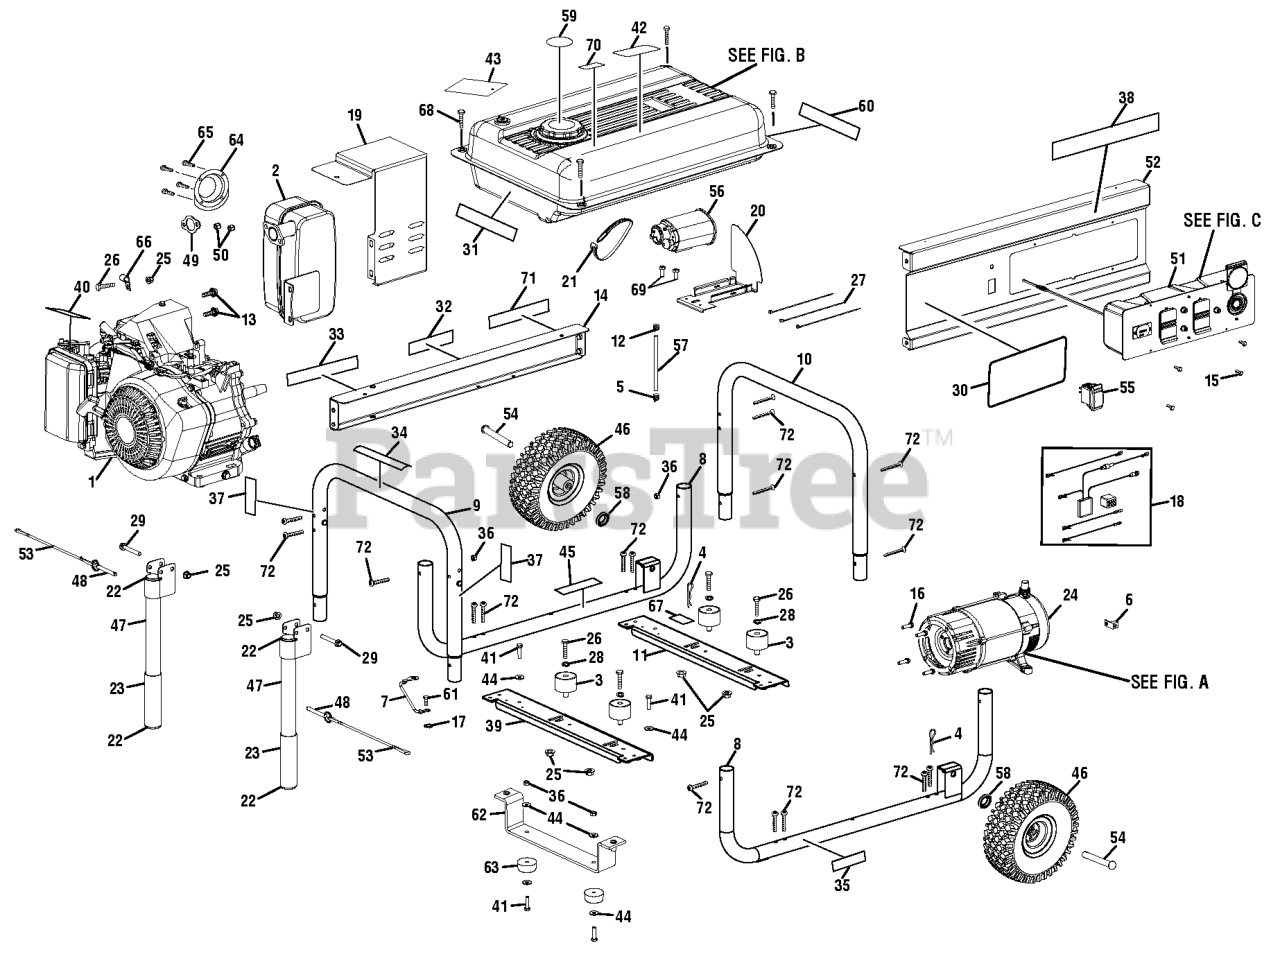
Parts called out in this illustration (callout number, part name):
1	Engine (Subaru)
4	Hitch Pin
5	Clamp (3/8 in.)
6	Ground Lug
7	Ground Wire Assembly
8	Lower Frame Assembly
9	Tube Assembly (Left)
10	Tube Assembly (Right)
11	Gen. Head Cross Brace
12	Clamp (1/2 in.)
13	Bolt (5/16-24 x 5/8 in.)
14	Back Panel
15	Screw (6-20 x 3/8 in.)
16	Bolt (3/8-16 x 1.25 in.)
17	Star Washer (M6)
18	Wire Harness
19	Heat Shield
20	Bracket (Carbon Canister)
21	Cable Tie (18.6 in.)
22	Plastic Cap
23	Handle Grip
24	Generator Head w/AVR
25	Lock Nut (M8)
26	Bolt (M8 x 35 mm, Hex Hd.)
27	Tie Wrap (5.5 in.)
28	Washer (M8)
29	Bolt (M8 x 55 mm, Hex Hd.)
30	Logo Label
31	Electric Start Label
32	Hot Surface Label
33	Danger Label
34	Fire Danger Label
35	Engine Lubricant Label
36	Lock Nut (M6)
37	Locking Pin Label
38	Subaru Label
39	Engine Cross Member
40	Choke Label
41	Bolt (M6 x 1 in., Hex Hd.)
42	CPSC Label
43	Danger Hang Tag
44	Washer (ID6.4 x OD17 x 1.6t)
45	Combustion Warning Label
47	Handle Assembly
48	Release Pin (5/16 x 2 in.)
49	Exhaust Gasket
50	Lock Nut (M8)
51	Panel Assembly
52	Front Panel
55	Start Switch w/Lock
56	Carbon Canister Assembly
57	Purge Hose
58	Washer (1/2 in.)
59	Fuel Stabilizer Label
60	Ground Warning Label
61	Screw (M6 x 16 mm, Hex Hd.)
62	Foot Bracket
63	Rubber Foot
64	Spark Arrestor
65	Screw (8-32 x 3/8 in., Pan Hd.)
66	J-Clamp (1/2 in.)
67	Ground Label
68	Screw (1/4-14 x 1-1/4 in.)
69	Screw (#10-16 x 3/4 in.)
70	E85 Label
71	Fire Distance Label
72	Screw (M6 x 50 mm, T30, Pan Hd.)
